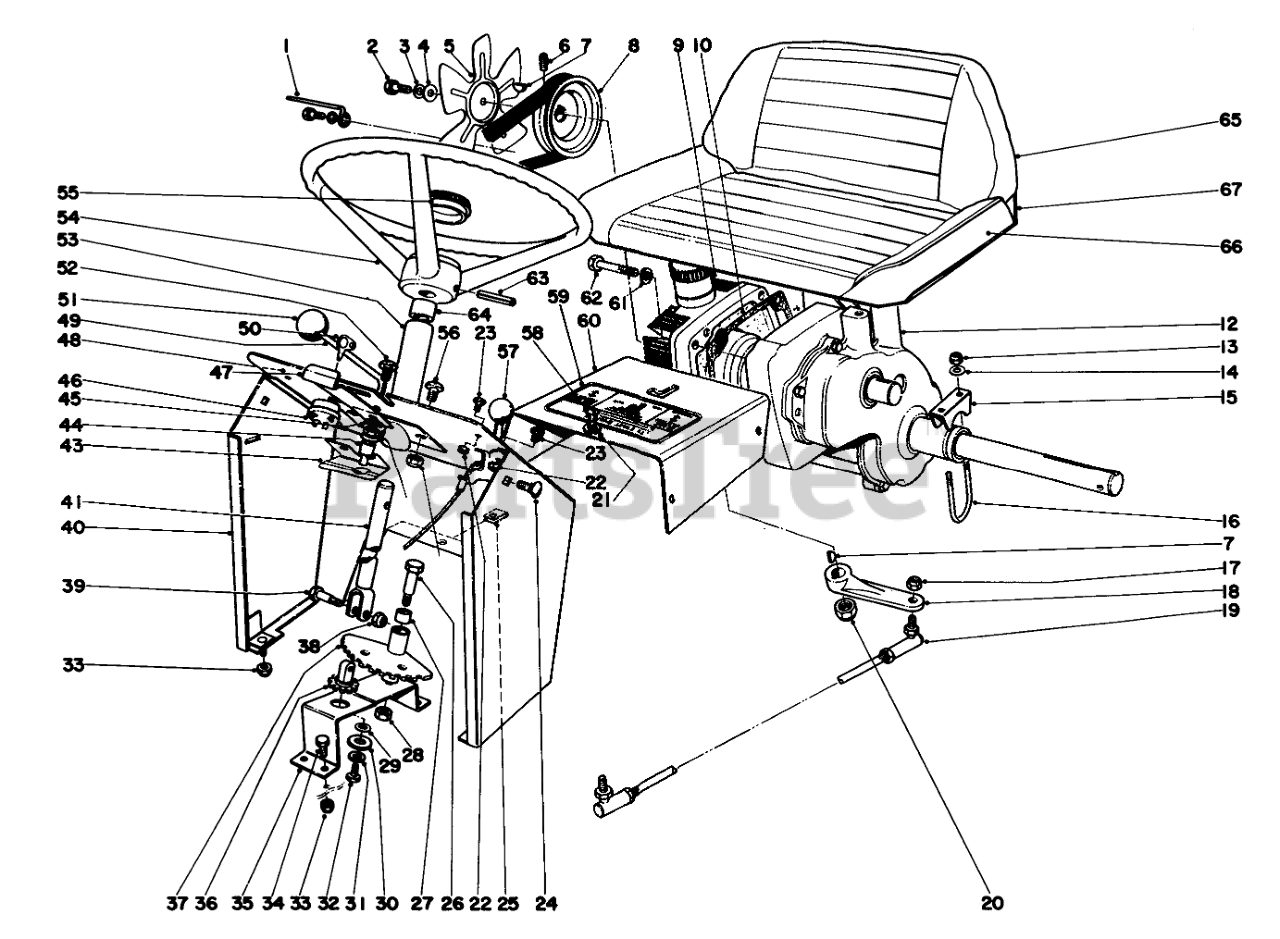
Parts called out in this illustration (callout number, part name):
1	Belt Guide
2	SCREW-HH
3	Lockwasher
4	WASHER-FLAT
6	SCREW-SET, HSH
7	KEY-WOODRUFF
8	Pulley
9	Hydrostatic Transmission
10	Gasket Transaxle
12	Transaxle
13	NUT-HEX
14	WASHER-FLAT
15	Axle Bracket
16	U-Bolt
17	NUT-HEX
18	Lever Hydrostatic
19	Control Rod Transmission
20	NUT-LOCK, CONE
21	WASHER-LOCK
22	Kep Nut
24	BOLT-CARR
25	SPEED NUT
26	Shoulder Bolt
27	BUSHING
28	Nut
29	Spacer
30	Washer
31	WASHER-LOCK
32	SCREW-HH
33	NUT-LOCK, CONE
34	SCREW-HH
35	Bracket
36	Pinion Steering
37	Gear Steering
38	NUT-HEX
39	Screw Shoulder
41	Steering Shaft
42	NUT-LOCK, CONE
43	Spring Detent
44	BUSHING
45	WASHER-FLAT
46	STARTER SWITCH
47	Hood Latch
48	Decal-Dash
49	Handle Hydro Control
50	Key
51	Knob
52	Carriage Bolt
53	Steering Tube Incl. Ref. #64
54	Steering Wheel
55	Steering Wheel Cap
56	Round Head Screw
57	Throttle Control
58	SCREW
59	Decal
60	Tunnel
61	WASHER-LOCK
62	SCREW-HH
63	PIN-ROLL
64	BUSHING
65	Seat Back
66	Seat Cushion
67	Frame-Seat
